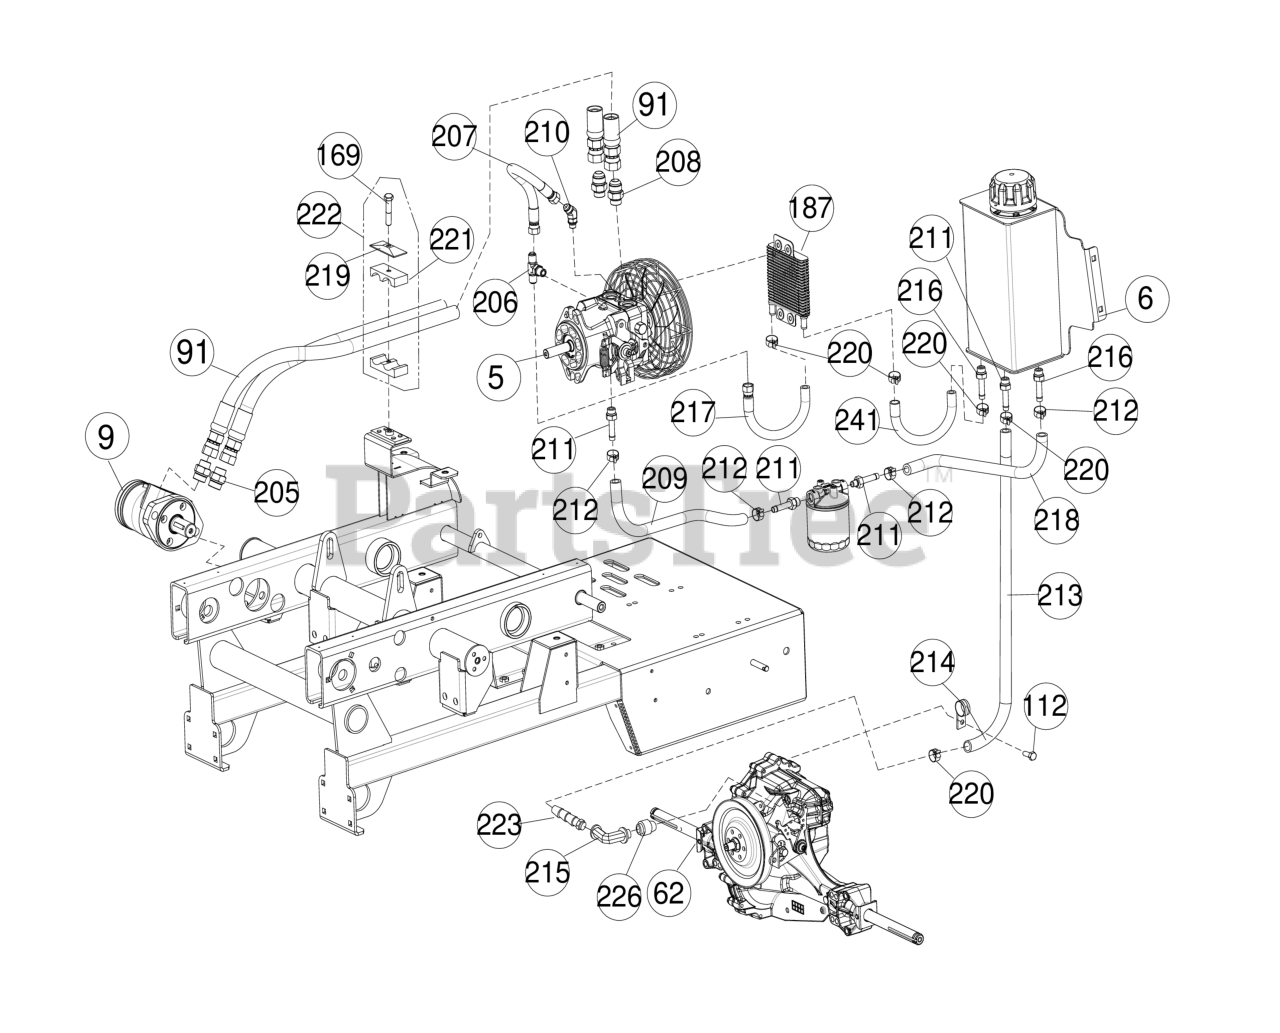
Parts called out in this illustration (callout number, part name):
5	PUMP PK 12CC VARIABLE DISPLACEMENT
9	MOTOR TINE DRIVE
91	HOSE HYDRAULIC W#10 JIC
112	SCREW SELF TAP 1/4"-20 X 5/8" HWH TYPE F
169	SCREWCAP 5/16"-18X2" HCS ZP
187	COOLER OIL
205	FITTING 10MJ - 10MOR STR
206	FITTING TEE 6803-06-06-06
207	HOSE ASSY #6 JIC TO RAW 11.00" LONG
208	FITTING 10MF 0- 8MORB STRAIGHT
209	HOSE, HIDRAULIC 1/2" X 12.00" LONG
210	FITTING 45 DEG 6802-06-04 W/0.050" ORIFICE
211	FITTING 08HB - 08MORB STRAIGHT
212	CLAMP MINIATURE WORM GEAR MAH6
213	HOSE HYDRAULIC 3/8" X 46.00" LONG
214	HOSE CLAMP
215	FITTING 90 DEG FEMALE TO FEMALE
216	FITTING 06HB - 06MORB STRAIGHT
217	HOSE ASSY #6 JIC TO RAW 13.00" LONG
217	HOSE HYDRAULIC 3/8" X 19" LONG
219	PLATE CLAMP COVER
220	CLAMP MINIATUE WORM GEAR MAH4
221	BODY PROFILED CLAMP
222	HYDRAULIC HOSE CLAMP
223	3/8" HOSE BARB
226	04MORB - 02MP STRAIGHT
241	HOSE HYDRAULIC 1/2" 14.00" LONG
